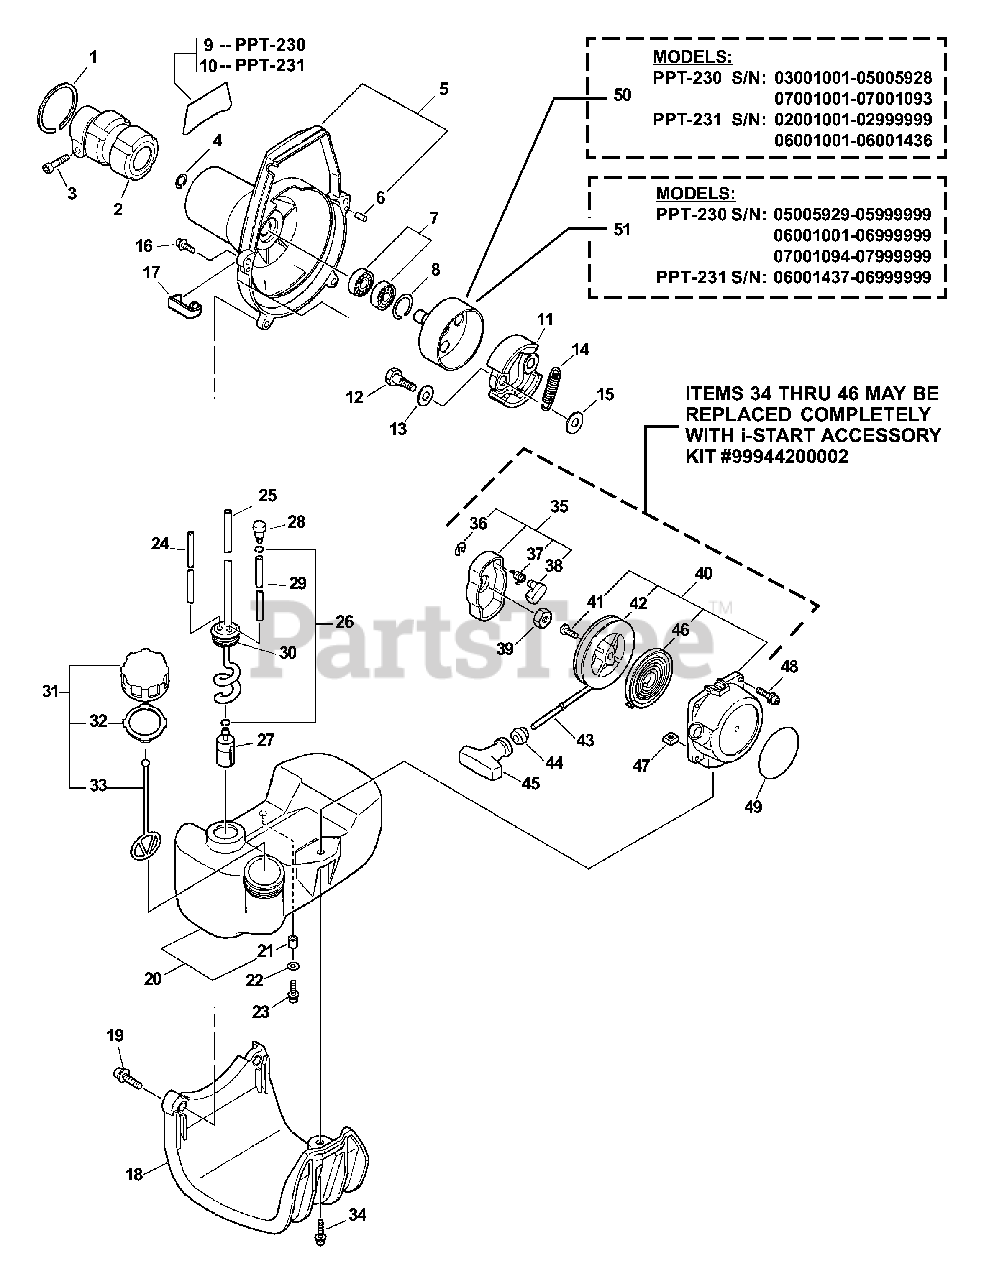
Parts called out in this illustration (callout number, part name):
1	RING, RETAINING - 42
2	CLAMP, MAIN PIPE
3	SCREW - 5X28
4	RING, RETAINING - 12
5	FAN CASE ASSY - ORANGE
6	PIN - LOCATING
7	BEARING, BALL - 6001
8	RING, RETAINING - 28
9	LABEL - MODEL PPT-230
10	LABEL - MODEL PPT-231
11	SHOE, CLUTCH
12	BOLT, CLUTCH
13	WASHER - SPRING
14	SPRING, CLUTCH
15	WASHER - 6
16	SCREW - 5X18
18	GUARD, FUEL TANK
19	SCREW - 5X22
20	FUEL TANK ASSY
22	WASHER - 5
23	SCREW - 5X16
24	PIPE - 3X6X80 -- CLEAR
25	PIPE - 3X6X170 -- BLACK
26	CLIP - 6.5
27	FILTER, FUEL
28	VENT, FUEL TANK
29	PIPE - 3X6X115 -- BLACK
30	GROMMET
31	CAP ASSY - ORANGE
32	GASKET, CAP
33	CONNECTOR, CAP
34	SCREW - 5X20
35	STARTER PAWL ASSY
36	RING, RETAINING - 4
37	SPRING, RETURN
38	PAWL, STARTER
40	STARTER ASSY
42	REEL, ROPE
43	ROPE, STARTER - 3.5X850
44	GUIDE, ROPE
45	GRIP, STARTER
46	SPRING, REWIND
47	NUT - 5 -- SQUARE
48	SCREW - 4X12
49	LABEL - ECHO
50	DRUM, CLUTCH
51	DRUM, CLUTCH
